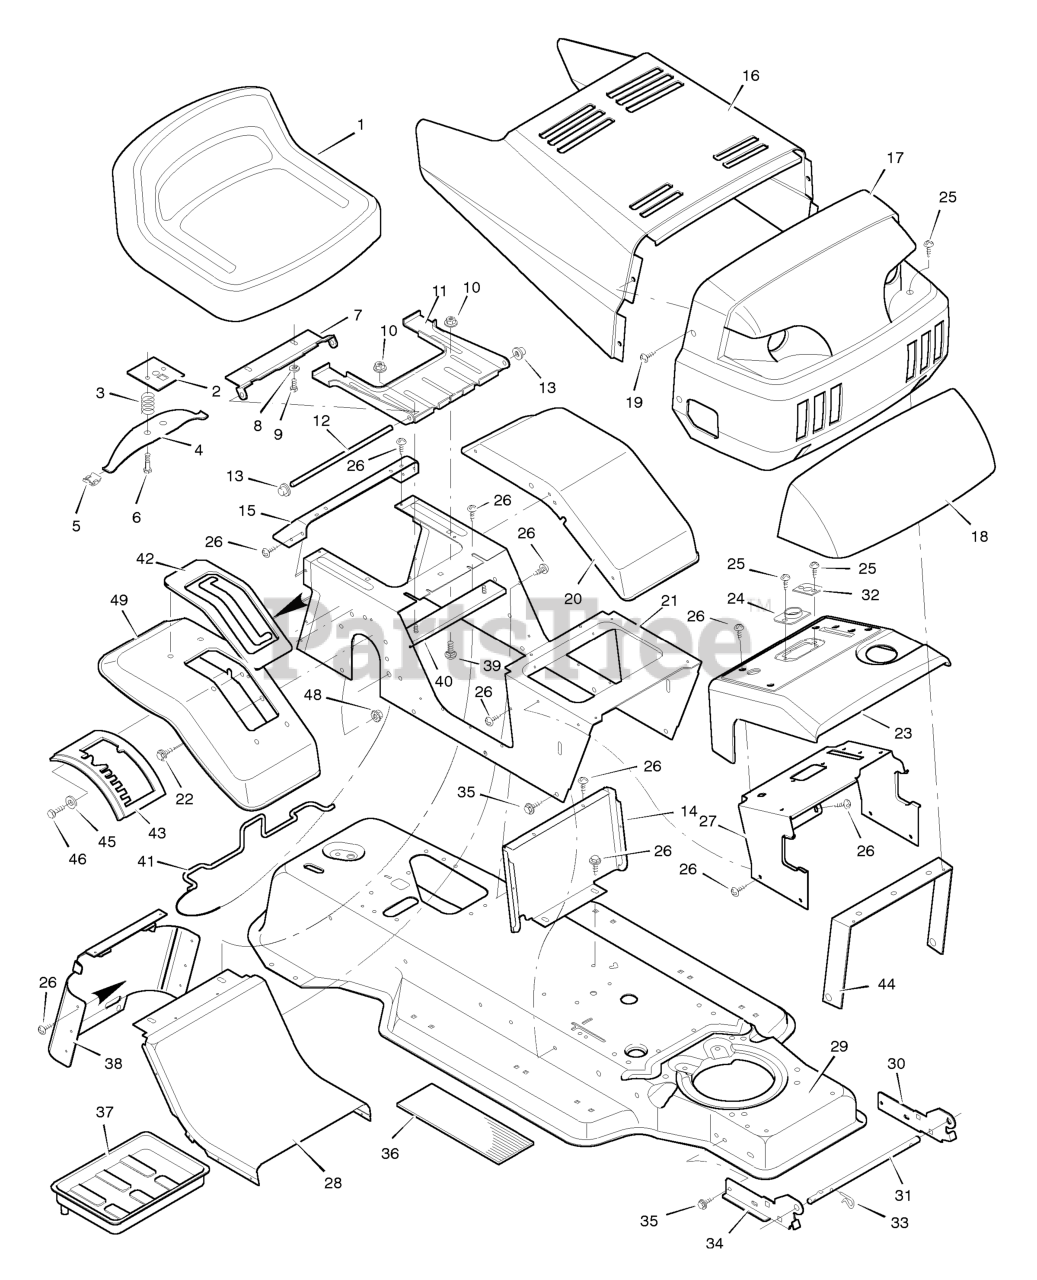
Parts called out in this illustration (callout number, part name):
2	Plate Assembly, Switch
3	Spring, Compression
4	Spring, Seat
5	Glide, Spring
6	Bolt, Shoulder
7	Support, Seat
8	Lockwasher
9	Bolt, Hex
10	Locknut, Flange
11	Bracket, Pivot
12	Rod, Pivot
13	Cap, Push On
14	Insert, Front
15	Fender, Apron
17	Grille Assembly
21	Console Assembly
23	Dash Panel
24	Bearing, Steering
26	Screw
27	Support, Dash
28	Insert, Rear
29	Frame Assembly
30	Bracket, Left Grille
31	Rod, Pivot
32	Bearing
33	Pin, Hair
34	Bracket, Right Grille
37	Tray, Battery
38	Cap, Console
39	Bolt
40	Channel Assembly
41	Clamp, Battery
42	Cover, Shift
43	Gate, Shift
44	Brace, Grille
45	Washer
46	Bolt, Hex
48	Locknut
49	Fender, SOG
